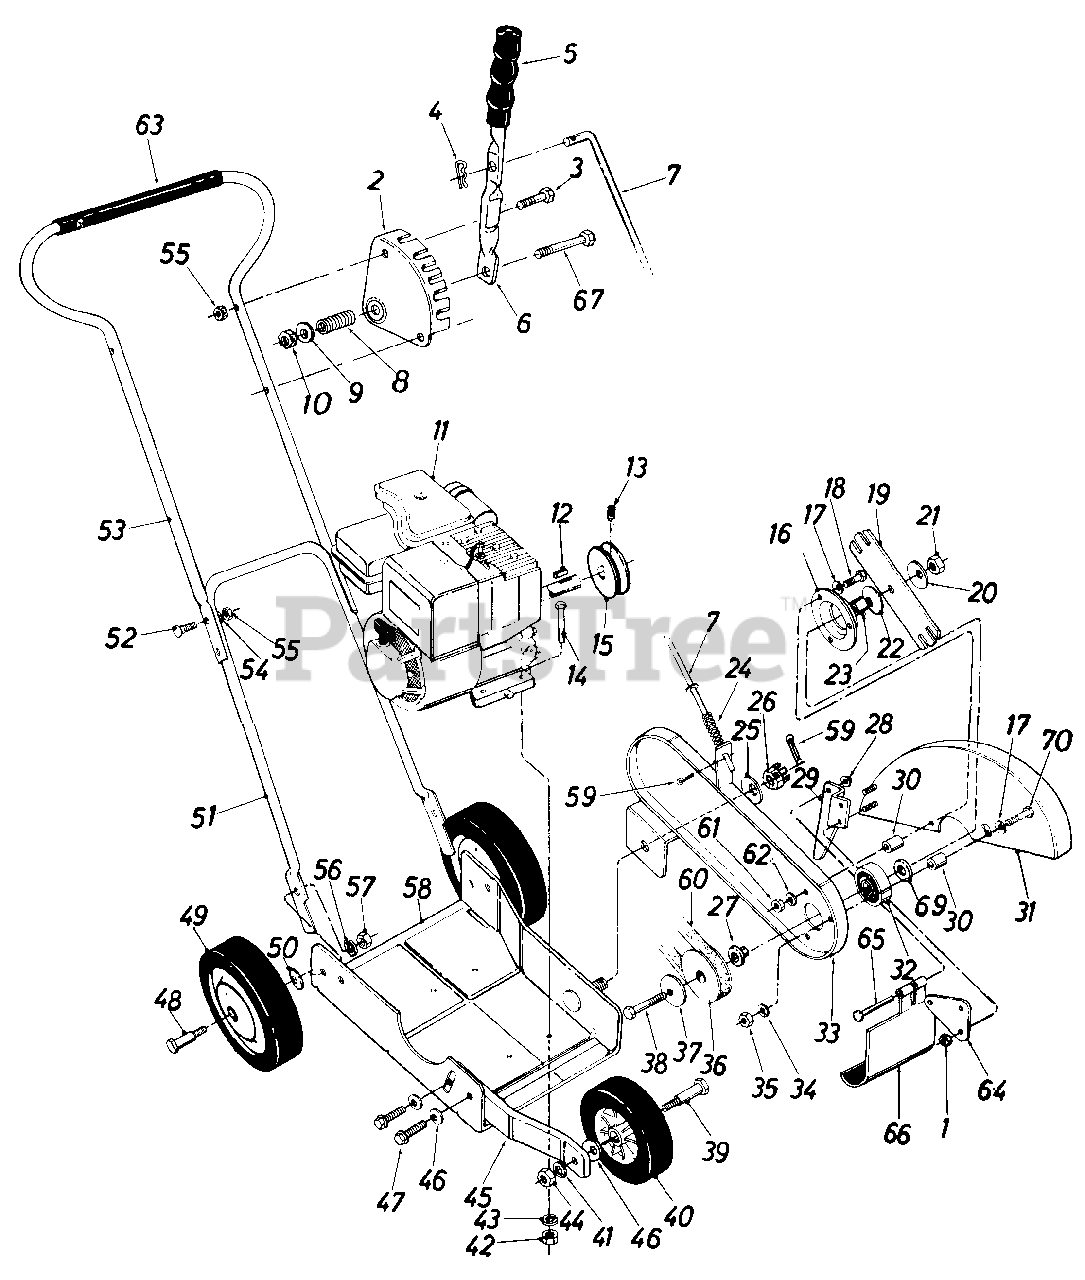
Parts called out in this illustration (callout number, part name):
1	Hex Cent. L.-Nut 1/4-20 Thd.
3	Hex Bolt 1/4-20 x 1.25" Lg.*
4	Cotter Pin 1/8" Dia. x 1.0" Lg.*
5	Grip
6	Clutch Handle
7	Clutch Rod
8	Compression Spring .50" O.D. x 1.38" Lg.
9	Fl.-Wash. .34" I.D. x .62" O.D. x.063
10	Hex Cent. L.-Nut 5/16-18 Thd
11	Engine
12	Sq. Key 3/16 x 1.0" Lg.*
13	Set Scr. 1/4-28 x 1/4" Lg.
14	Hex Bolt 5/16-18 x 1.50' Lg.*
15	Engine Pulley
16	Bearing Housing
17	Bell.-Wash. .34" I.D. x 88" O.D. x .060
18	Hex Bolt 5/16-18 x 1.25" Lg.*
20	Bell.-Wash. .535" I.D. x 1.50" O.D. x.052
21	Hex Cent. L.-Nut 1/2-20 Thd.
22	Bell.-Wash. .535" I.D. x 1.50" O.D. x .052
23	Spacer
24	Compression Spring .57" O.D. x 1.92" Lg.
25	Bell.-Wash. .535 " I.D. x 1.50" O.D. x .052
26	Hex Castle Nut 1/2-20 Thd.
27	Shoulder Spacer
28	Push Cap
29	Guide
30	Spacer .354" I.D. x .635" O.D. x .510" Lg.
33	Spindle Bracket Ass'y.
34	L.-Wash. 5/16" I.D.*
35	Hex Nut 5/16-18 Thd.
36	Pulley
37	Bell.-Wash. .535" I.D. x 1.50" O.D. x.052
38	Hex Bolt 1/2-20 x 3.50" Lg.*
39	Shoulder Bolt .498" Dia. x 1 .450
40	Wheel Ass'y.Comp.6" Dia x 1.50
41	L.-Wash. 3/8" I.D.*
42	Hex Nut 5/16-18 Thd.*
43	L.-Wash. 5/16" I.D.*
44	Hex Nut 3/8-16 Thd.*
45	Front Wheel Support
46	Bell.-Wash. .400" I.D. x 88" O.D. x.060
47	Hex Wash. Hd. Self Tap Scr. 3/8-16 x .75 " Lg.
48	Shoulder Bolt .498" Dia. x 1 .450
49	Wheel Ass'y. Comp. 7" Dia x 1.50
50	Bell.-Wash. .400" I.D. x 88" O.D.
51	Lower Handle
52	Carriage Bolt 1/4-20 x 1.25" Lg.*
53	Upper Handle
54	L.-Wash. 1/4" I.D.*
55	Hex Nut 1/4-20 Thd.*
56	L.-Wash. 3/8" I.D.*
57	Hex Nut3/8-16Thd.*
58	615 Base Ass'y.
59	Cotter Pin 1/8" Dia. x 1.0" Lg.*
60	3V-Belt31.2" Lg.
61	Hex Nut 5/16-18 Thd.*
62	L.-Wash.5/16" I.D.*
63	Grip (Optional)
64	Flap Bracket
65	Hinge Pin
66	Debris Deflector
67	Hex Bolt 5/16-18 x 1.75" Lg.*
69	Fl.-Wash. .51 I.D. x 1.00 O.D. x.060
70	Hex Bolt 5/16-18 x 2.00" Lg.*
